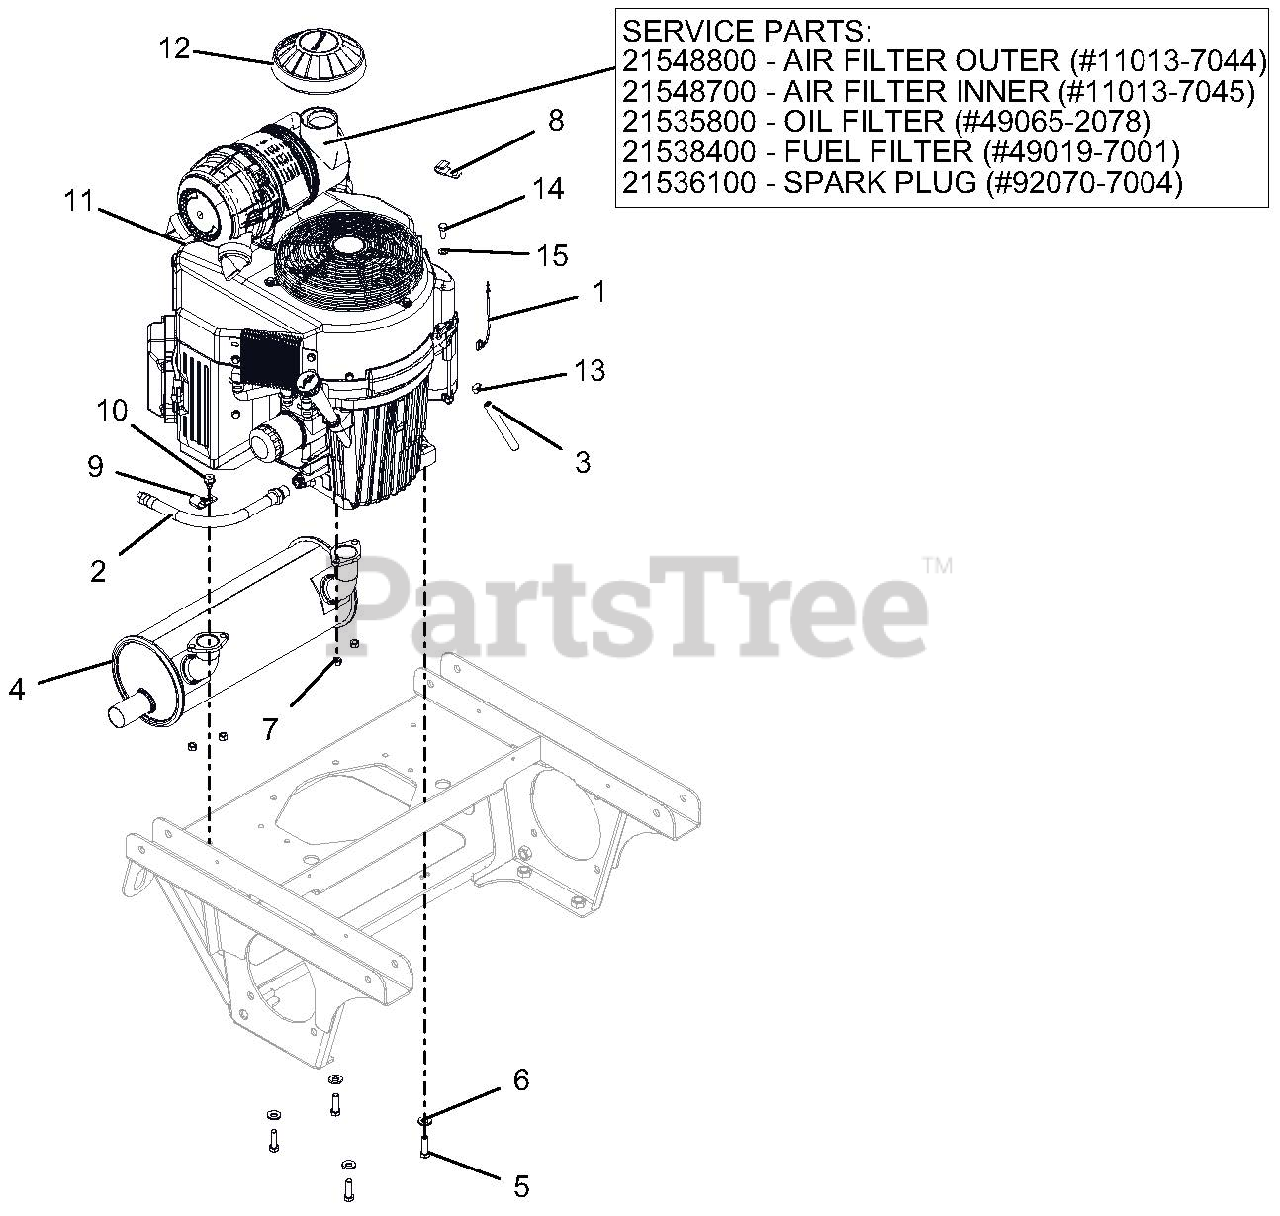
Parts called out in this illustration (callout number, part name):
1	LEAD - STARTER SOLENOID
2	HOSE, OIL DRAIN
3	.25 LOW-PERM GAS HOSE 28.00" LG - VALVE TO ENGINE
4	MUFFLER - 34HP KAWASAKI VERT
5	BLT-HEX .38-16X1.25 GR5 YWZC NYTORQ
6	WSHR, 3/8" SPRING DISC
7	NUT-LK-TOP M8-1.25 YWZC
8	CLAMP, J
10	SCR-TAP .38-16X.50 HWH TR YWZ
11	ENGINE, KAWASAKI FX921
11	AIR FILTER OUTER
11	AIR FILTER INNER
11	OIL FILTER
11	FUEL FILTER
11	SPARK PLUG
12	CAP, AIR CLEANER INTAKE
13	CLAMP, FUEL LINE
14	@BLT-HEX M8-1.25X20 YWZC
15	WSHR-LK .31X.078 REG YWZC
